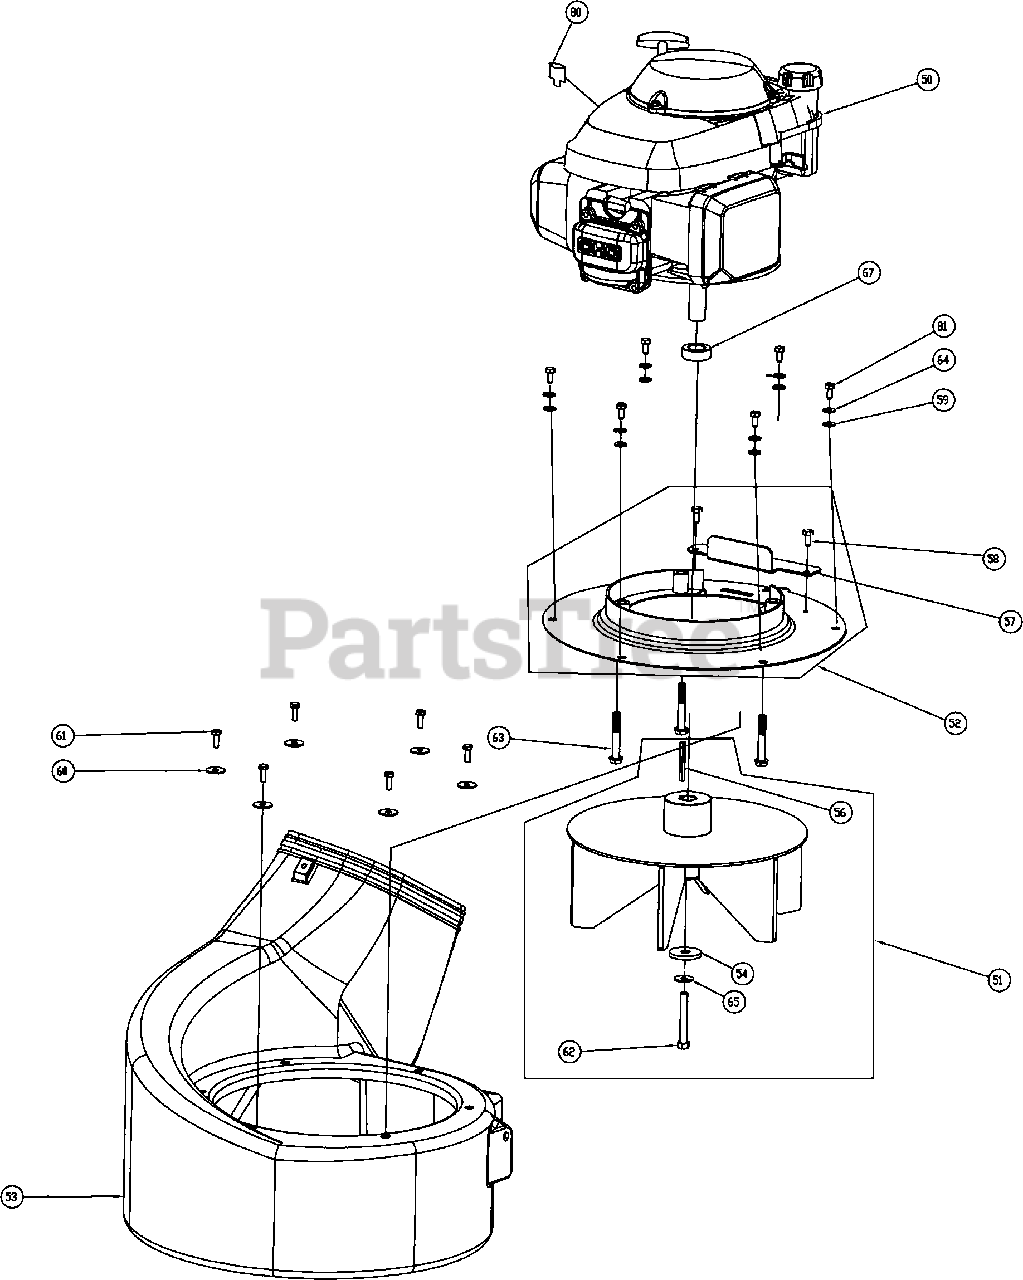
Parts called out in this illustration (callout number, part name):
50	ENGINE HONDA 6.5 VERTICAL GSV190
51	IMPELLER ASSEMBLY PUSH MV VAC
52	TOP PLATE ASSEMBLY PUSH MV VAC
53	HOUSING PLASTIC VAC
54	WASHER 1.5 OD X .453 ID X .25 THK
56	SQ KEY 2.125 X .187
57	BRACKET COVER TOP PLATE VAC
58	SCREW 1/4"-20 X 5/8" HWH
59	WASHER 1/4" SAE ZP
60	WASHER FENDER 1/4 ZP
61	SCREWCAP 1/4 - 20 x 0.75 HWH
62	SCREWCAP 3/8-24X2 3/4" W/PATCH LOCK
63	SCREWCAP 3/8"-16X2 1/2" TAPTITE
64	WASHER SPLIT LOCK 1/4"
65	WASHER LOCK 3/8" ST MED
67	SPACER 1.50OD X .875ID X .5 THK
80	TERMINAL 18-14 BLUE T-TAP
81	SCREWCAP 1/4-20X5/8 GR. 5
